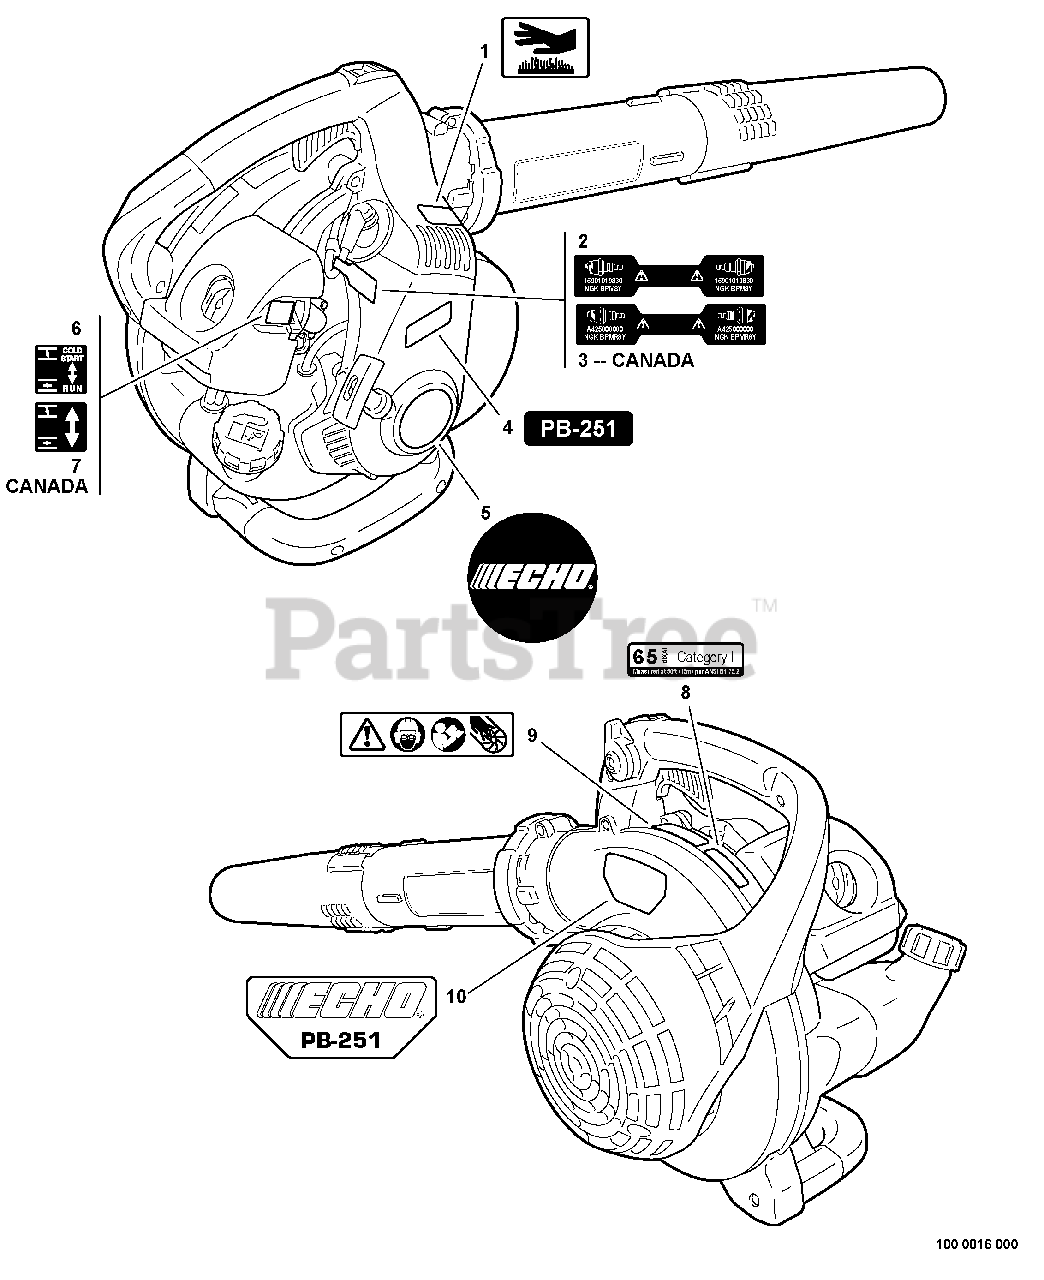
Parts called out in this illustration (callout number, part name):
1	LABEL, CAUTION - HOT
2	LABEL, SPARK PLUG - BPM8Y
3	LABEL, SPARK PLUG - BPMR8Y
4	LABEL, MODEL
5	LABEL, RECOIL STARTER
6	LABEL, CHOKE
7	LABEL, CHOKE
8	LABEL, NOISE
9	LABEL, CAUTION - ISO
10	LABEL - MODEL PB-251
